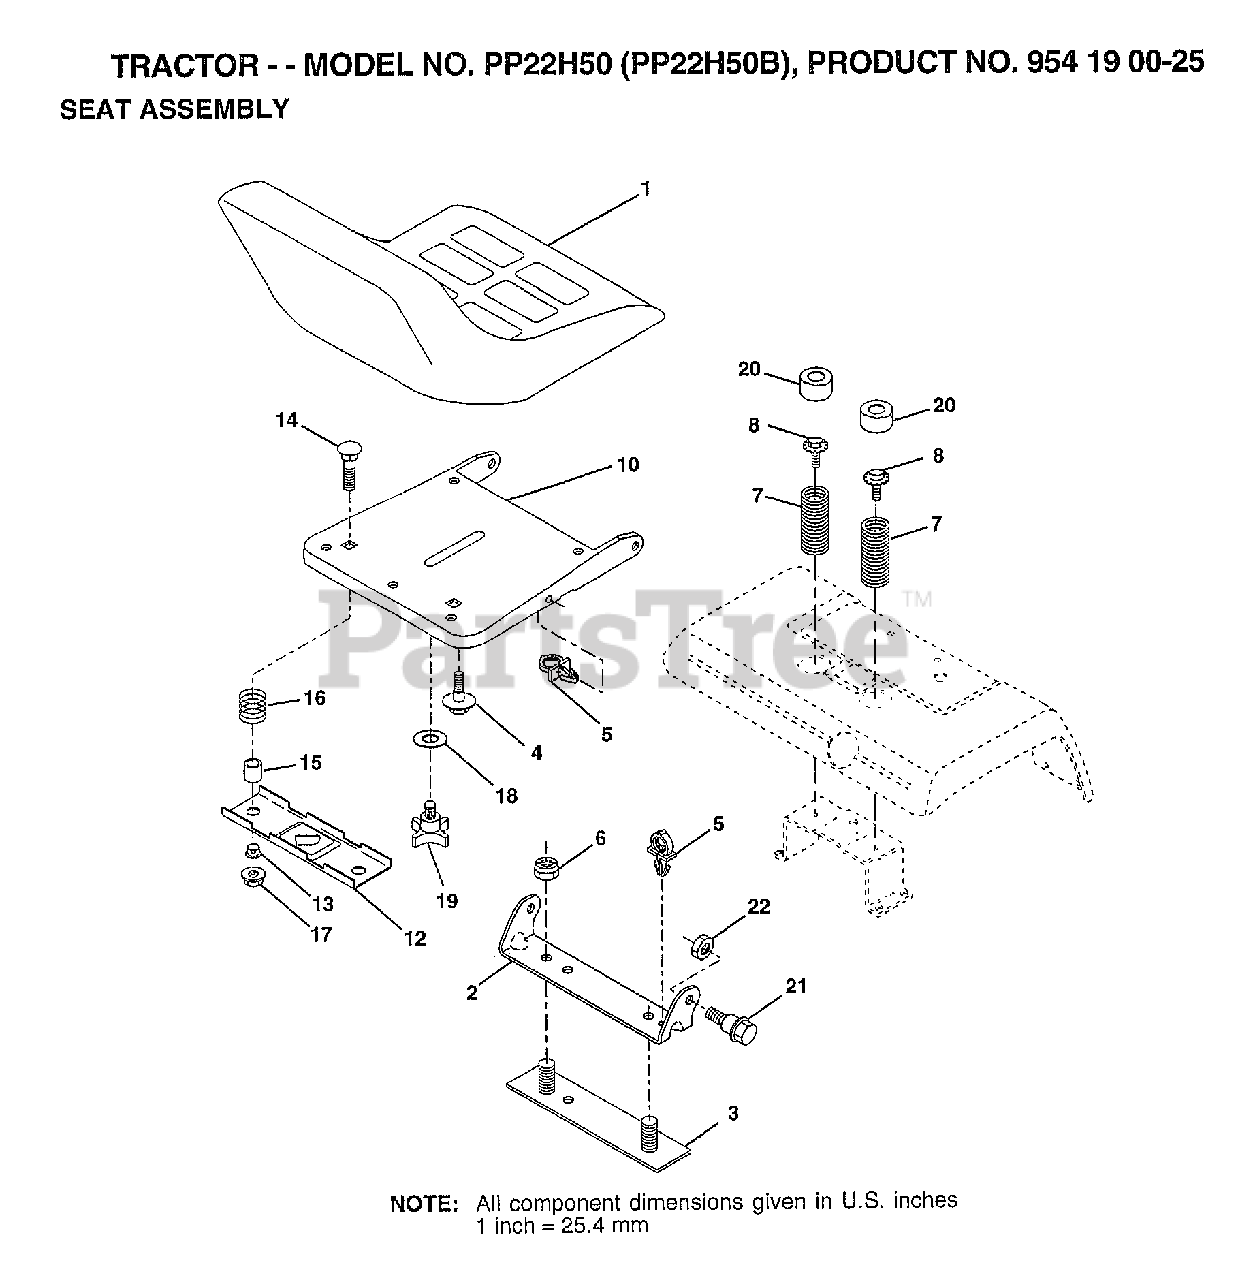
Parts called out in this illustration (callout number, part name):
2	BRACKET PVT SEAT
3	STRAP ASM FENDER
4	"BOLT,SHOULDER"
5	CLIP.PUSH-IN.HING
7	SPRING COMPRESSIO
8	BOLT.5/16-18.UNC
10	PAN-SEAT
12	BRKT SWITCH
13	BUSHING
14	BOLT-RD HD SQ NK
15	SPACER SPLIT
16	SPRING COMPRESSED
18	WASHER
19	"KNOB 1/2"" YT"
20	CAP SPRING
21	"BOLT,SHOULDER"
